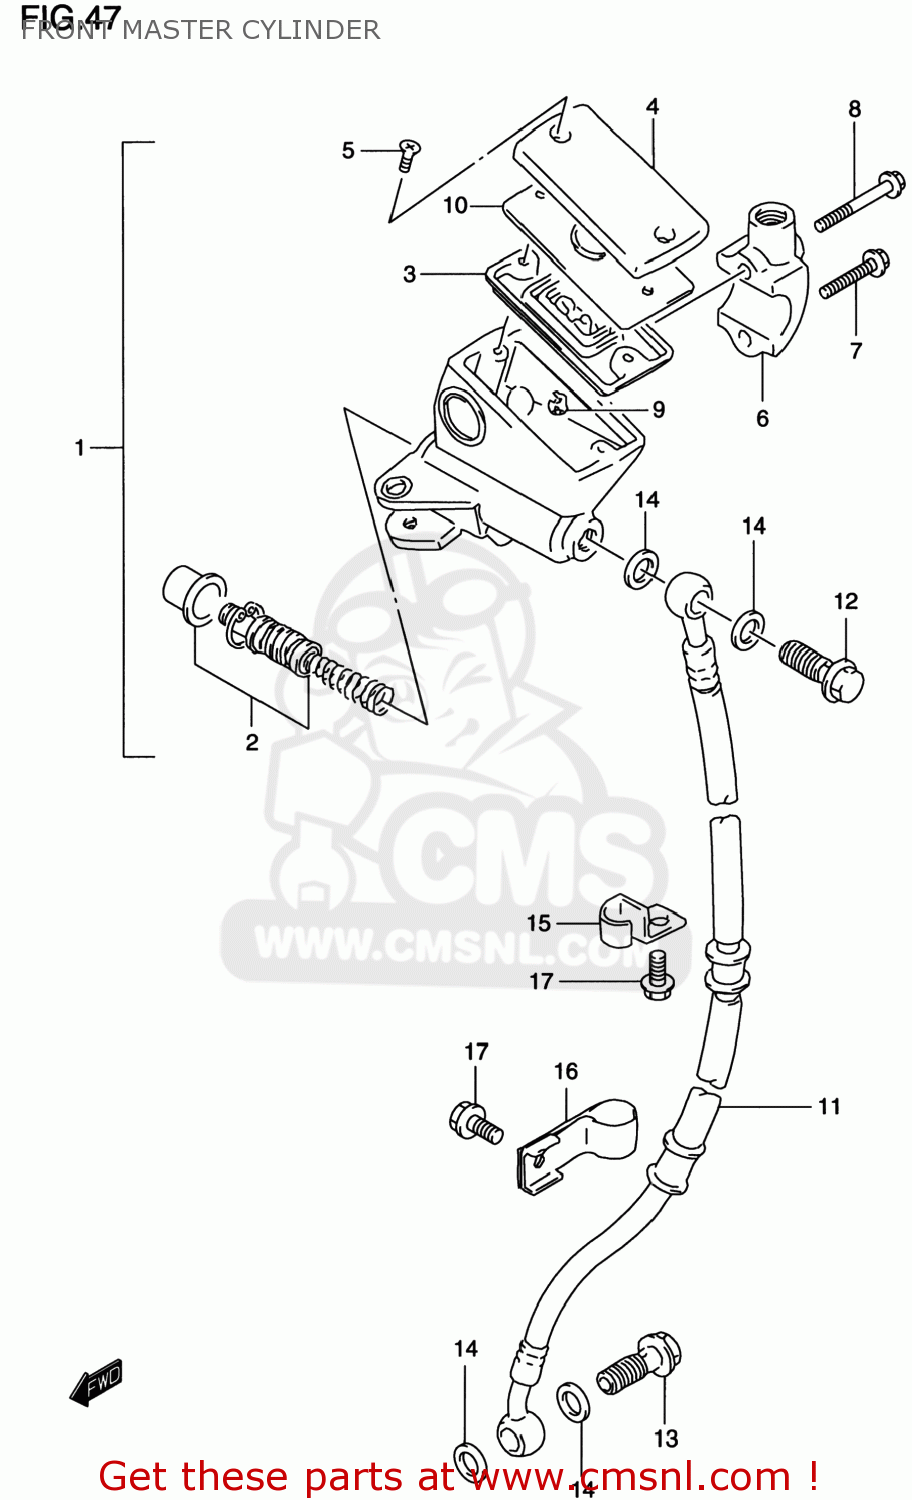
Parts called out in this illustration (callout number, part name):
1	CYLINDER ASSY,FR MASTER
2	PISTON/CUP SET
3	4
4	CAP
5	SCREW
6	HOLDER
7	BOLT(6X25)
8	BOLT(6X38)
9	PROTECTOR
10	PLATE,DIAPHRAGM
11	HOSE,FR BRAKE,R
12	BOLT UNION
13	BOLT UNION
14	WASHER(10X15X1.5)
15	CLAMP,FR BRAKE HOSE
16	CLAMP,FRONT BRAKE NO.2
17	BOLT
